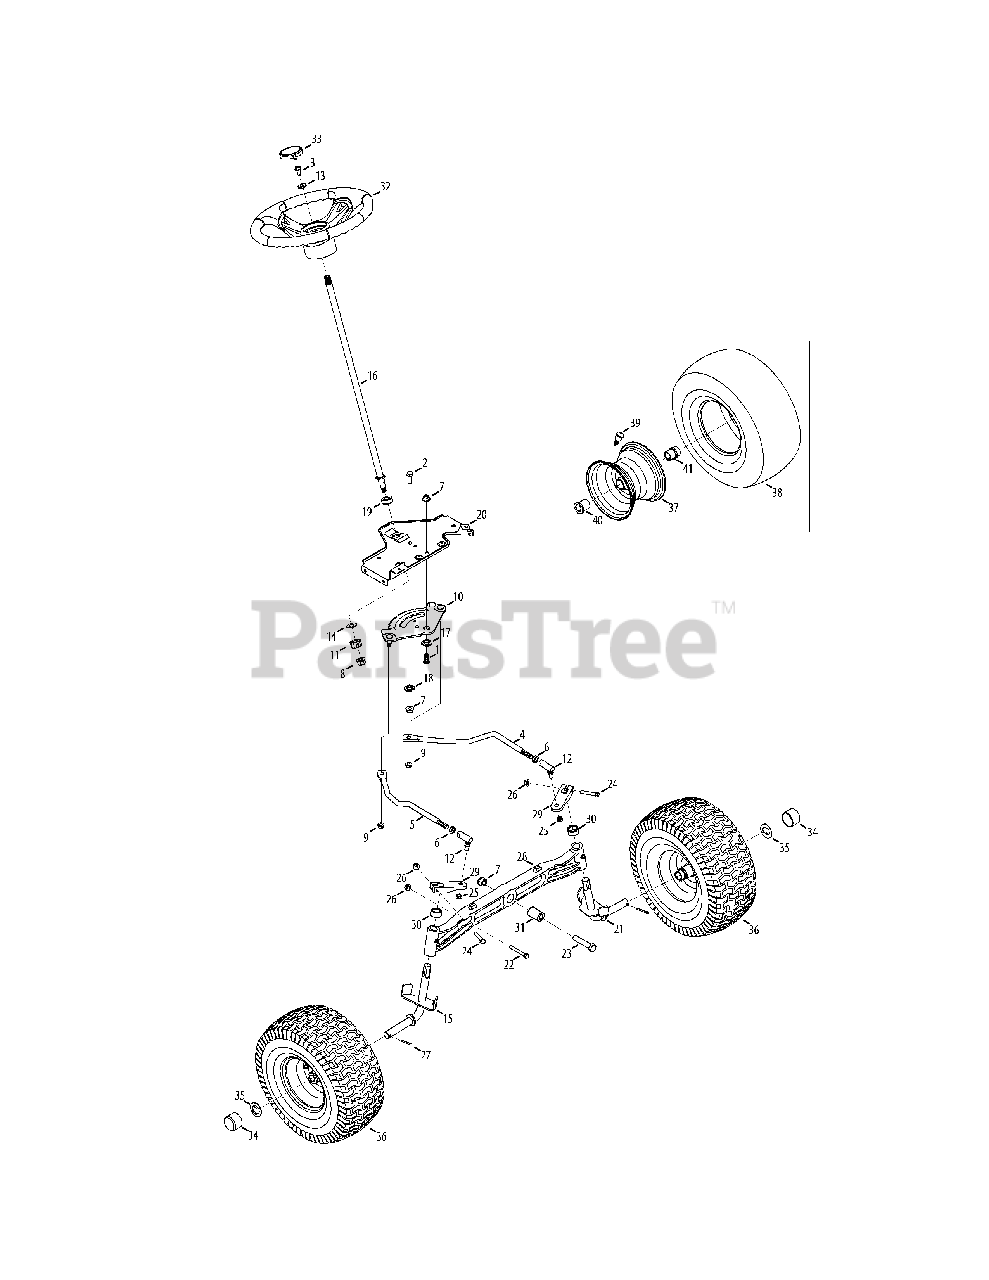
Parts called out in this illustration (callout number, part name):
1	Hex Head Screw, 3/8-16:1.00
2	Hex Head Screw, 3/8-16:1.00
3	Hex Head Screw, 5/16-18:1.00
4	LH Drag Link
5	RH Drag Link
6	Jam Nut, 7/16-20
7	Flangelock Nut, 3/8-16
8	Flangelock Nut, 7/16-20
9	Flangelock Nut, 5/16-18
10	Steering Gear
11	Steering Pinion Gear
12	Ball Joint, 7/16-20
13	Flat Washer, .406 x .875 x .105
14	Flat Washer, .51 x 1.12 x .06:HT
15	RH Axle Assembly
16	Steering Shaft, .625 OD x 24.25 LG
17	Shoulder Spacer, .385X 1.25 x .3025
18	Spacer, .38 x 1.375
19	Hex Flange Bearing 5/8 PM
21	LH Axle Assembly
22	Hex Head Screw, 5/16-18:2.25
23	Hex Head Screw, 3/8-16:2.50
24	Hex Head Screw, 5/16-18:1.75
25	Hexlock Nut, 3/8-24
26	Flangelock Nut, 5/16-18
27	Cotter Pin, 5/32:1.25
28	Pivot Bar Axle
29	Steering Block
30	Spacer, .71 ID x .125 OD x .56LG
31	Spacer, .385 x 1.00 x 1.5075
32	Steering Wheel
33	Steering Wheel Cap, TB
34	Bumper Cap
35	Flat Washer, .781ID x 1.590OD
36	Wheel Assembly
37	Rim Assembly
39	Tubeless Air Valve
40	Flange Bearing, .760 x 1.00 x 1.20LG
41	Flange Bearing, .76 ID w/ Lube Fitting
